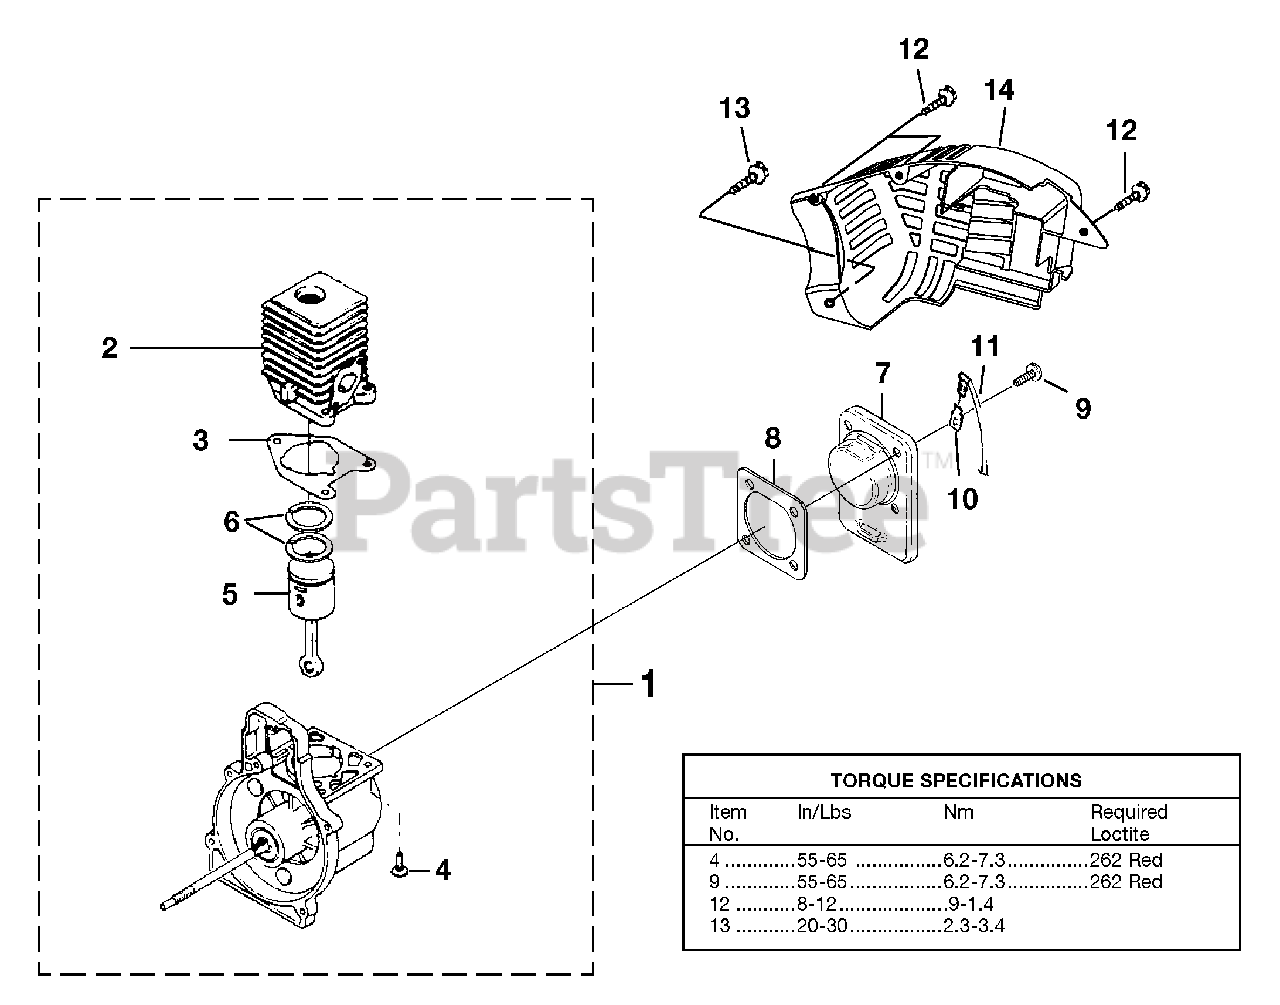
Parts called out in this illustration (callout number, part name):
1	SHORT BLOCK (30cc)
2	30 CC CYLINDER
3	GASKET-Cylinder
4	SCREW, SEMS (12-24 x 3/4)
5	30 CC PISTON & ROD
6	RING-Piston
7	CRANKCASE COVER
8	GASKET-Crankcase
9	SCREW, SEMS (10-24 x .56)
10	TAB-Male
11	Lead-Ground to Handle
12	SCREW-Thread Form. (#8 X 1/2)
13	SCREW-Thread Form. (#10 X 3/4)
